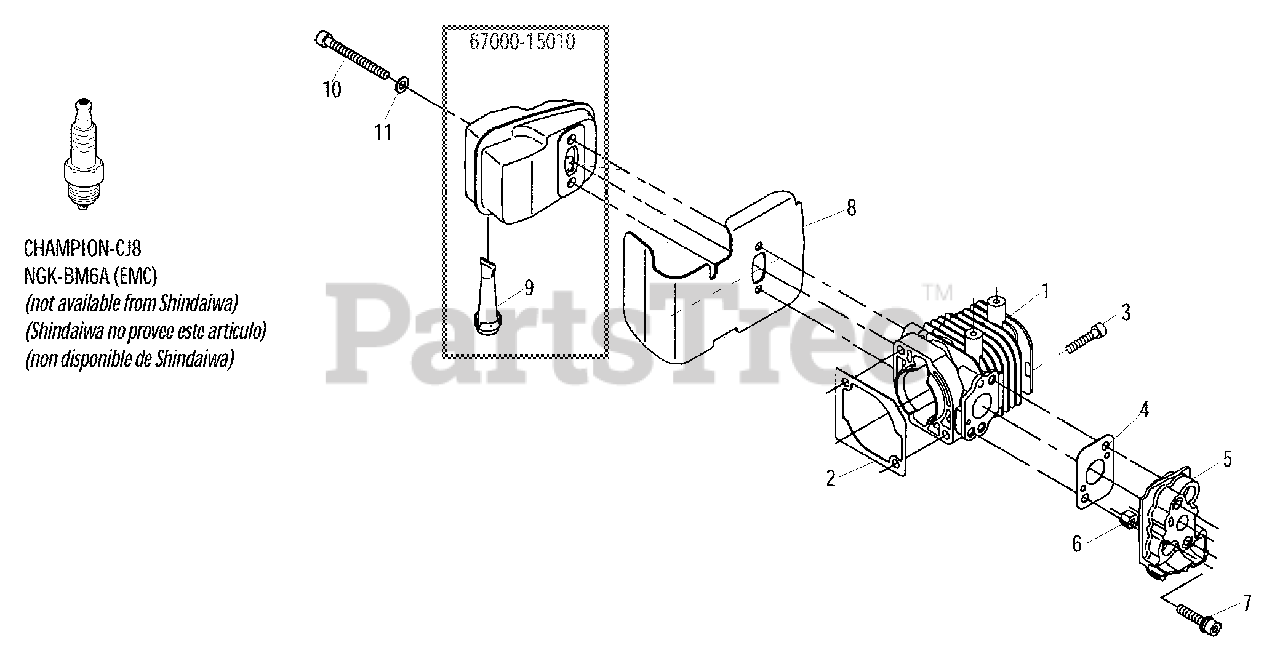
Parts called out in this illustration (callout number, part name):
1	CYLINDER
2	GASKET, CYLINDER
3	SCREW - 5X25
4	GASKET
5	INSULATOR
6	NUT
7	SCREW - 5X25
8	GASKET, EXHAUST
9	SCREEN, SPARK ARRESTOR
10	SCREW - 5X40
11	WASHER - 5
67000-15010	MUFFLER ASSY
